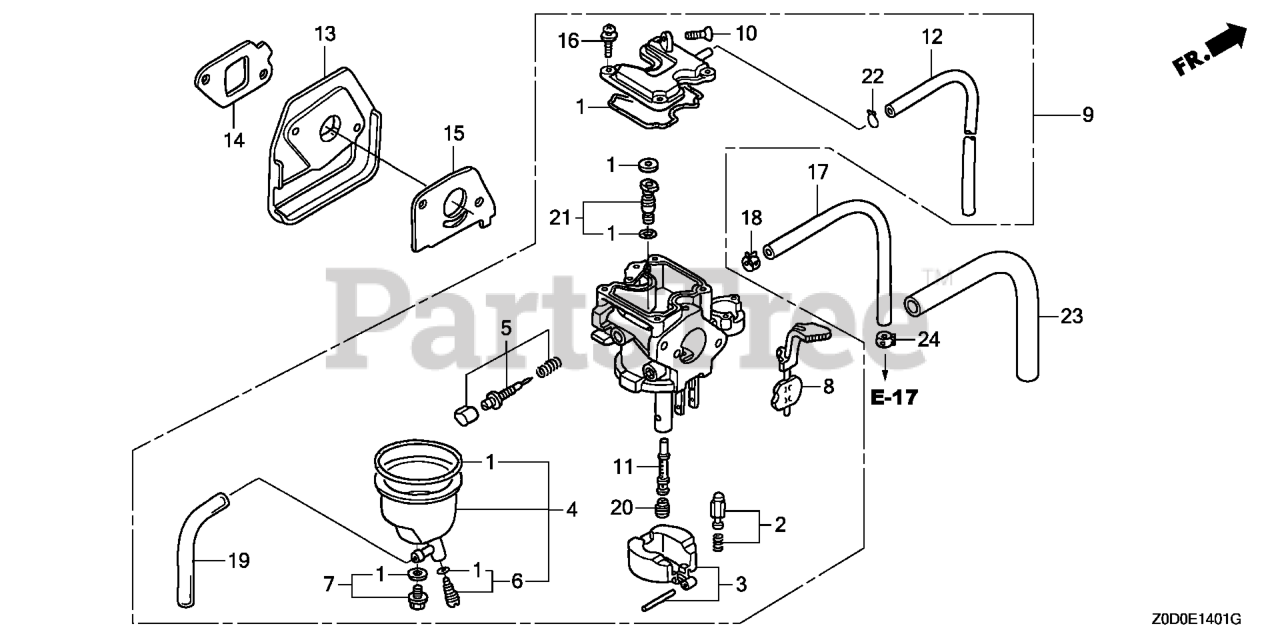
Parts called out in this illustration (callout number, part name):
1	GASKET SET (CARBURETOR NO.)
2	VALVE SET, FLOAT (CARBURETOR NO.) (SEAT NOT INCLUDED)
4	CHAMBER SET, FLOAT (CARBURETOR NO.)
6	SCREW SET, DRAIN (CARBURETOR NO.)
7	SCREW SET (CARBURETOR NO.)
8	LEVER SET, CHOKE
9	CARBURETOR ASSY. (BF33D C)
10	SCREW, THROTTLE STOP
11	NOZZLE, MAIN
12	TUBE, AIR VENT
13	INSULATOR, CARBURETOR
14	GASKET, INSULATOR
15	GASKET, CARBURETOR
16	SCREW-WASHER (4X12)
17	BULK HOSE, FUEL (4.5X3000) (4.5X120)
18	CLIP, TUBE (D8.5)
19	BULK HOSE, VINYL (3.5X6.5X8000) (9500(95003-05001-60M) (CARBURETOR NO.)
20	JET, MAIN (#55) Use from Engine SN BF22B D.
20	JET, MAIN (#58) Use from Engine SN BF22B D.
20	JET, MAIN (#60)
21	JET SET, PILOT (#35)
22	CLIP, TUBE (B1 8)
24	CLIP, TUBE (D8.5)
